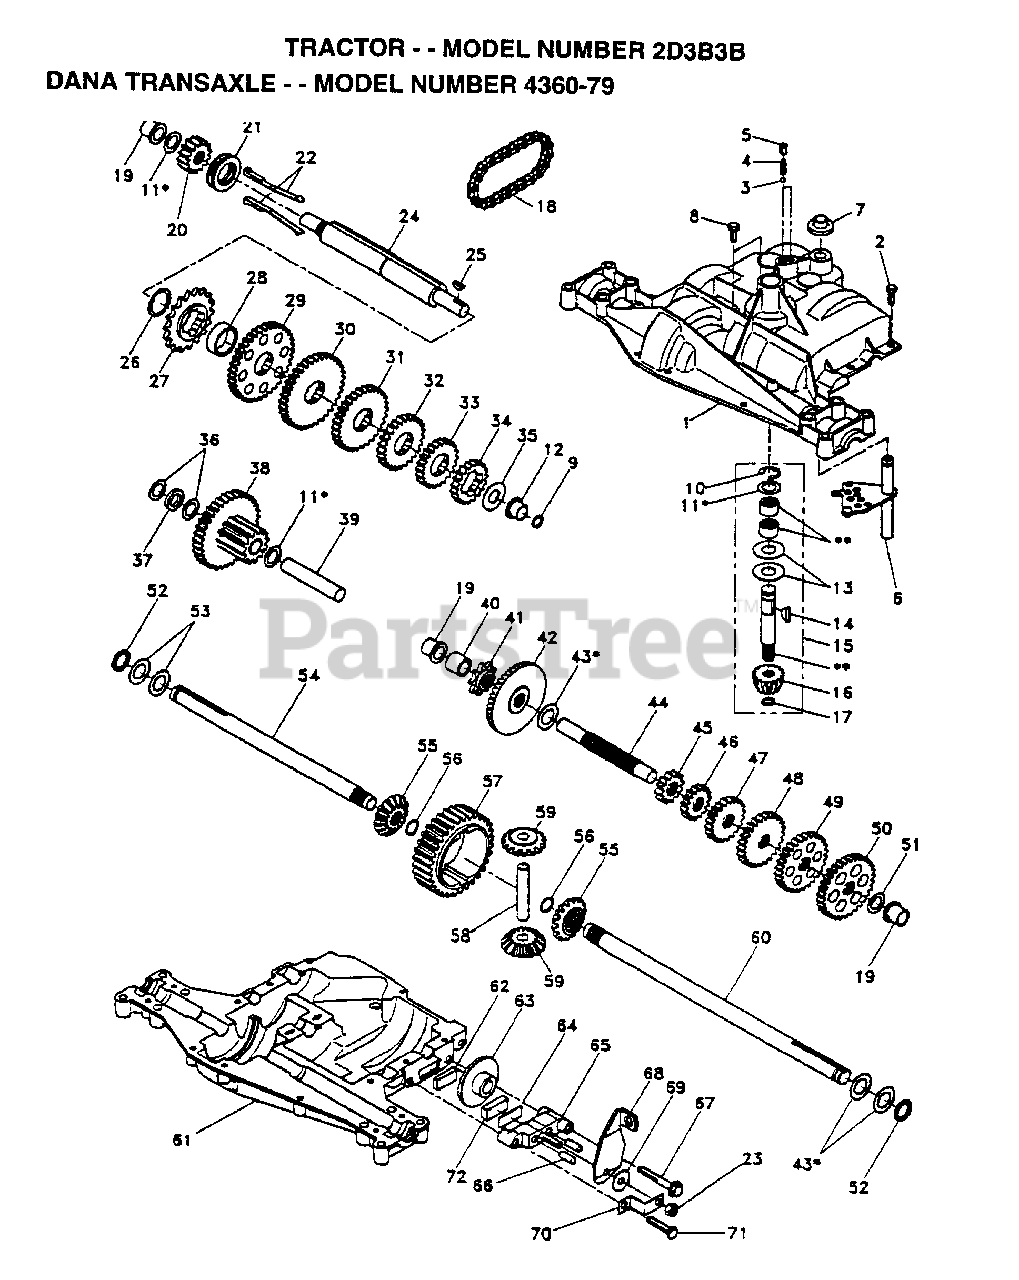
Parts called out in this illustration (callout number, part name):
1	HOUSING UPPER TRN
4	"SPRING, DETENT LT"
5	"SCREW, SET LT"
6	KIT SHIFTER ASM
7	SHIFTER BOOT
8	SCREW TAP W/SEAL
9	SQUARE RING
11	ASM KIT SHIM 4689
12	BEARING FLAN-DANA
13	WASHER T
14	KEY WOODRUFF-DANA
15	AS KIT INPUT SHFT
16	PINION 14T T
17	"RING,RETAINING LT"
18	"CHAIN,24 PTCH LT"
19	BEARING.FLNG.5510
20	GEAR SPUR 14 TTH
21	COLLAR CLUTCH
22	ASM KIT CLTCH KEY
23	NUT.LOCK.5/16-24
24	SHAFT INTERM DANA
25	WOODRUFF KEY
26	"RING,RETAINING LT"
27	SPROCKET 18T T
28	SPACER YT
29	GEAR SPUR 37 TTH
30	GEAR SPUR 35 TTH
32	GEAR 25T LT
33	GEAR SPUR 22 TT
34	SPUR GEAR 19T
35	"WASHER, PLAIN LT"
36	WASHER 025
37	SPACER
38	ASSM GEAR COMB
39	SHAFT IDLER
40	SPACER T
41	SPROCKET 9T LT
43	ASM KIT SHIM
44	SHAFT T
45	GEAR SPUR 12 TTH
46	GEAR SPUR 15 TTH
48	"GEAR, SPUR 25T LT"
49	GEAR 28T T
50	"GEAR, SPUR 31T LT"
51	WASHER 060
52	NEOPRENE WASHER
53	WASHER 031
55	GEAR 15T T
56	"RING,RETAINING LT"
58	SHAFT T
59	GEAR 1ST T
61	HOUSING LOWER TNS
62	PUCK T
63	BRAKE DISC. T
64	SPACER LT
66	PIN T
69	WASHER LT
71	"SCREW, TAPPING LT"
72	PUCK T
